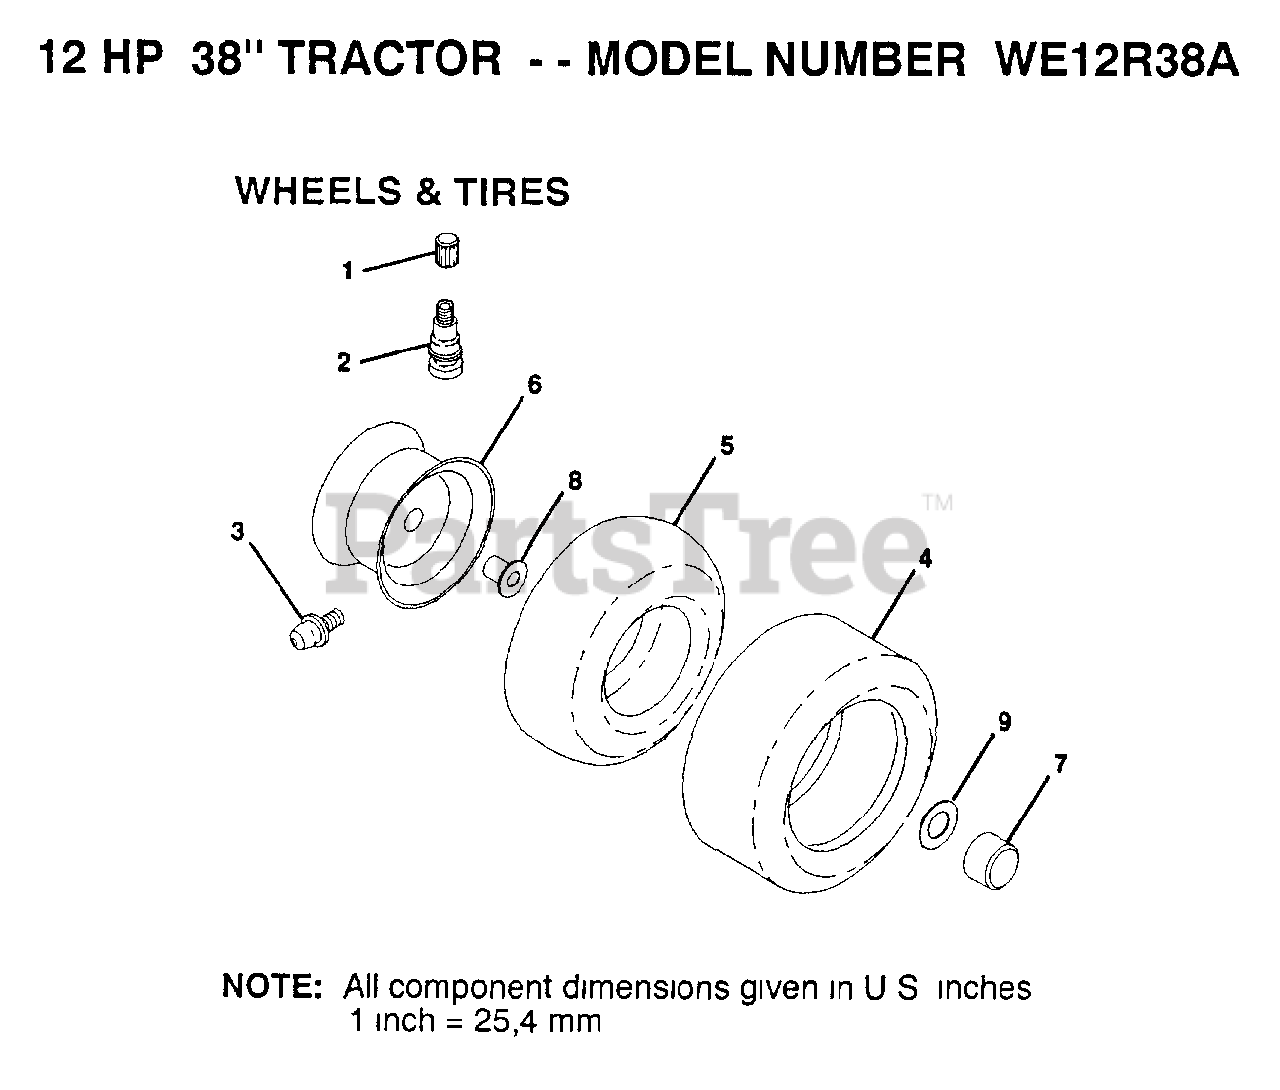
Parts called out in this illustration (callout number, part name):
1	VALVE CAP
2	VALVE STEM LT
3	FITTING LT
5	TUBE.5.3/4.5/6
6	RIM, ASSEMNLY, FRONT
7	HUB CAP
8	"FLANGE, BEARING"
9	WASHER
